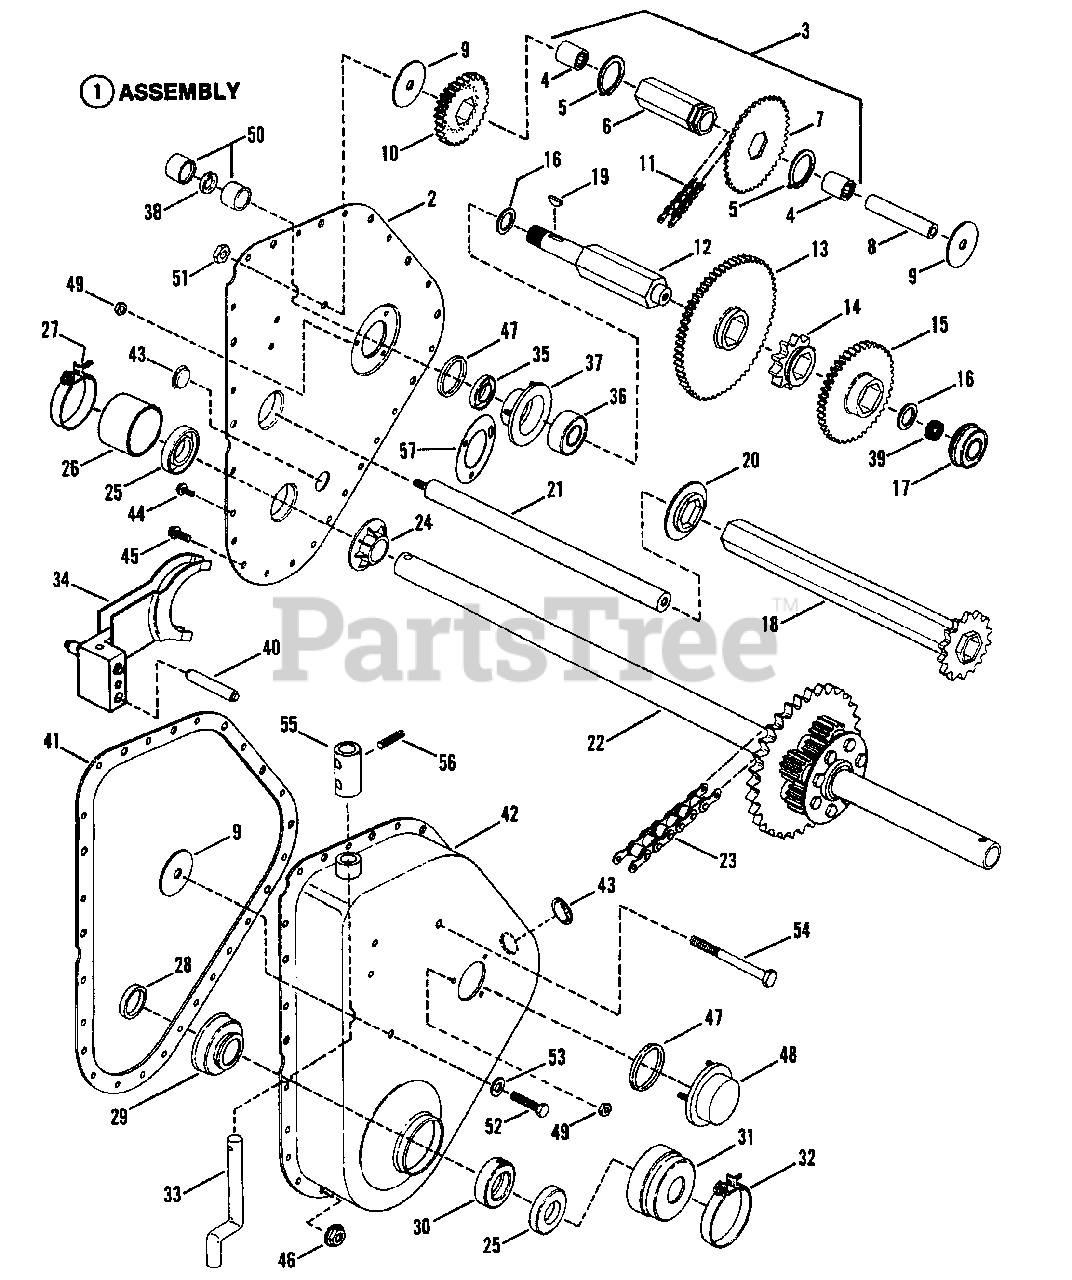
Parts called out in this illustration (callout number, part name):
1	ASSEMBLY, TRANSMISSION
2	COVER, Transmission
3	ASSEMBLY, Hex Tube (Short)
4	BEARING, Needle
5	RING, Retaining
6	TUBE, Hex
7	SPROCKET, 46 Tooth (#35)
8	RACE, Bearing
9	THRUST WASHER
10	CLUSTER GEAR
11	CHAIN, 56 Pitch (#35)
12	SHAFT, Third Reduction
13	GEAR, 67 Tooth, 12 Pitch
14	SPROCKET, 10 Tooth (#50)
15	GEAR, 47 Tooth, 12 Pitch
16	SHIM WASHER
17	BEARING
18	ASSEMBLY, Drive Hex Tube
19	KEY, Woodruff (#9)
20	SPECIAL WASHER (Hex Insert)
21	SHAFT, Drive Tube Support
22	DIFFERENTIAL
23	CHAIN, 42 Pitch (050)
24	SPECIAL WASHER
25	OIL SEAL
26	CAP, Seal
27	CLAMP, 1-7/8" Hose
28	SPACER, Bearing
29	BEARING, Ball
30	COLLAR, Lock
31	CAP, Dust Seal
32	CLAMP, For 2.69" Hose
33	ROD, (HI-LO Range) Shift
34	ASSEMBLY, HI-LO Shifter
35	SEAL, Oil
36	BEARING
37	ASSEMBLY, Bearing Retainer
38	"O"-RING
39	RING, Tolerance
40	GUIDE-PIN, Shift
41	GASKET, Cover to Case
42	ASSEMBLY, Transmission Case
43	PLUG, Oil Fill & Check
44	SCREW, 1/4-20 x 5/8" HWF Self Tap
45	BOLT, 1/4-20 x 1/2" HWF (2-Locating)
46	NUT, 1/4-20 Hex Flange Lock
47	"O"-RING
48	ASSEMBLY, Bearing Retainer
49	NUT, 1/4-20 Hex Flange Lock
50	SPACER, Brake Shaft
51	NUT, 3/8-16 Hex Top Lock
52	SCREW, 3/8-16 x 3/4" Hex Head Cap, Grade 5
53	WASHER, 3/8 Split Lock
54	SCREW, 3/8-16 x 3-1/4" Hex Head Cap
55	COUPLING, Shift Lever
56	ROLL-PIN, 3/16 X 3/4"
57	GASKET, Bearing Retainer
